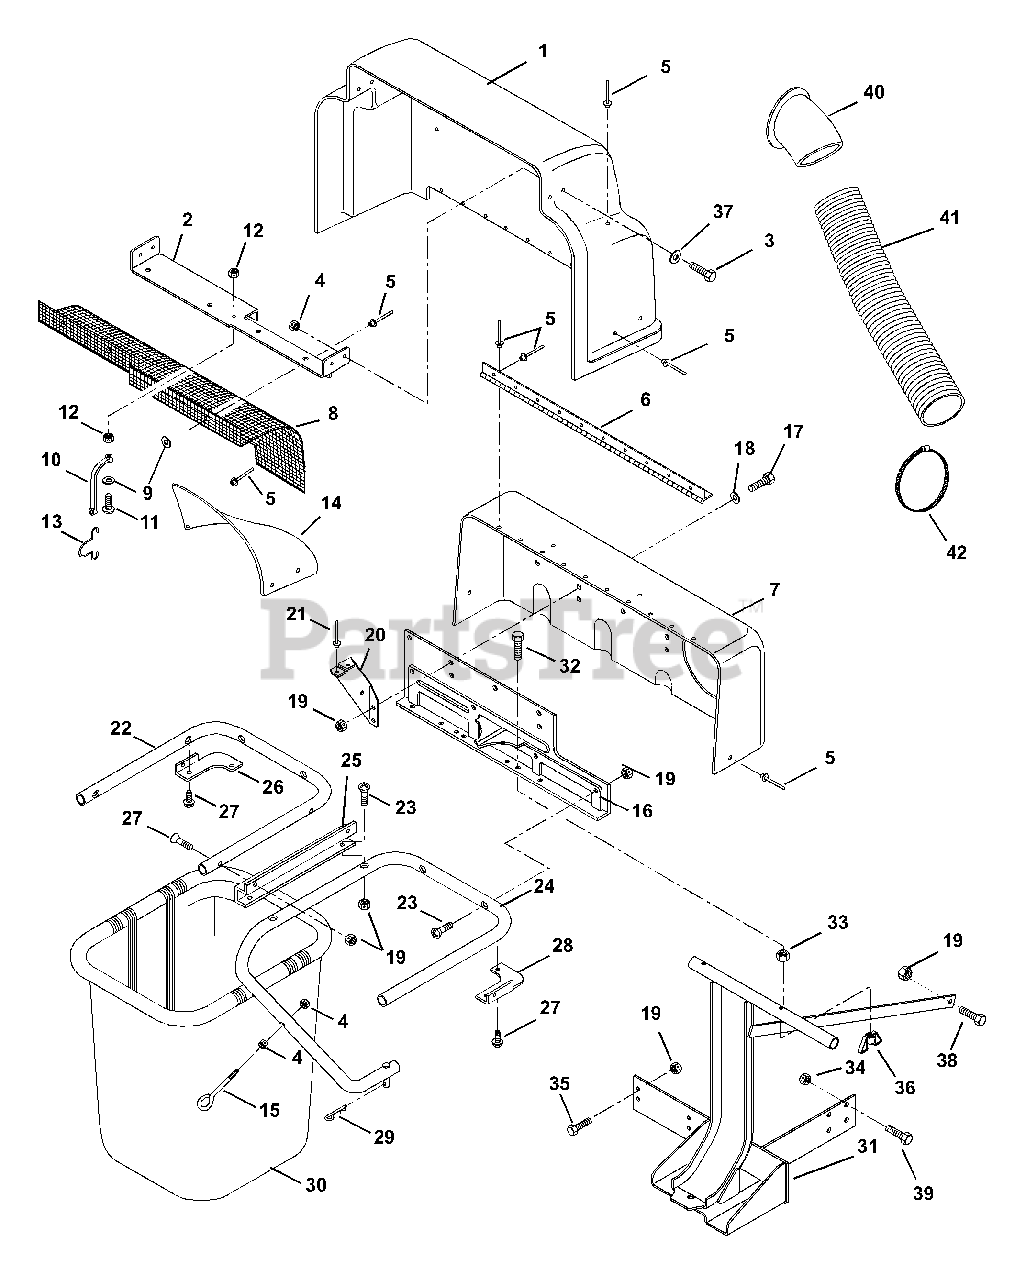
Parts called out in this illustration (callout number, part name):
1	Hinged Cover
2	Cover Bracket
3	Bolt-Hex .25-20 x .50 Grade 2
4	Nut-Locking-Center .250-20
5	Rivet-Pop .187 x .402
7	Stationary Cover
9	Washer-Flat-Steel .219 x .50 x .049
10	Battery Strap
11	Screw-Machine 10-24 x .88
12	Nut-Locking Top 10-24
16	Mounting Bracket
17	Bolt-Hex .31-18 x .88 Grade 2
18	Washer-Flat-Steel .328 x .875 x .062
19	Nut-Locking .312-18
21	Rivet-Pop .187 x .527
22	Center Tube
23	Screw-Machine .31-18 x 1.50
24	Right Tube
25	Tube Bracket
26	Left Hand Corner Bracket
27	Screw-Tapping .31-18 x .50
28	Right Hand Corner Bracket
29	Pin-Hair Internal .08 x .38 x 1.42
30	Grass Bagger Basket
31	Bagger Frame
32	Bolt-Hex .31-18 x 1.50 Grade 2
33	Nut-Hex .31-18 Grade 2
34	Nut-Locking-Center .38-16 Grade 2
35	Bolt-Hex .31-18 x 1.00 Grade 5
36	Nut-Wing .312-18
37	Washer-flat-Steel .281 x .62 x .065
38	Bolt-Hex .31-18 x 0.75 Grade 5
39	Bolt-Hex .38-16 x 1.00 Grade 5
40	Upper Bagger Boot
41	Hose 7 x 45"
42	Clamp, Hose
